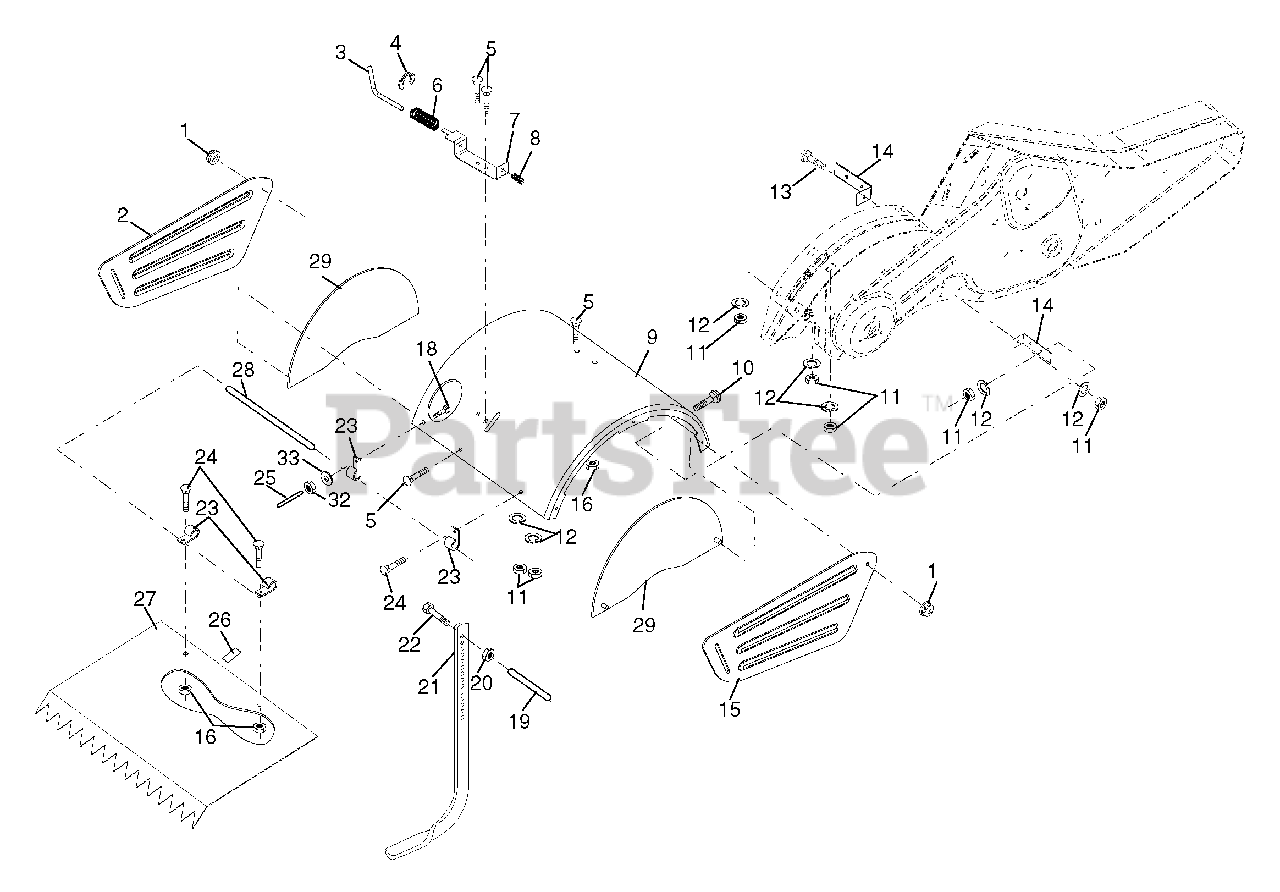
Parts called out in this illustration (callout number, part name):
1	Nut, Lock Hex Flange 5/16-18
2	Shield, Side, Outer L. H.
3	Pin, Stake, Depth
4	Ring, Klip
5	Bolt, Rdhd Sqnk 5/16-18 x 3/4
7	Bracket, Latch
8	Spring, Depth Stake
9	Shield, Tine
10	Bolt, Carriage 5/16-18 unc x 1
11	Nut, Hex 5/16-18
12	Washer, Lock 5/16
13	Bolt, Carriage 5/16-18 x 1-1/4
14	Bracket, Shield Tine
15	Shield, Side, Outer R.H.
16	Nut, Hex Flange 1/4-20 unc
18	Bolt, Carriage 1/4-20 x 1-1/4 Gr. 5
20	Nut, Hex 3/8-16
21	Stake, Depth
22	Bolt, Hex 3/8-16 x 2
24	Bolt, Carriage 1/4-20 x 1/2 Gr. 5
25	Cap, Vinyl
26	Pad, Idler
27	Shield, Leveling
28	Pin, Hinge
29	Shield, Side
32	Nut Fin Hex 1/4-20 unc
33	Washer Lock Hvy Helical 1/4
